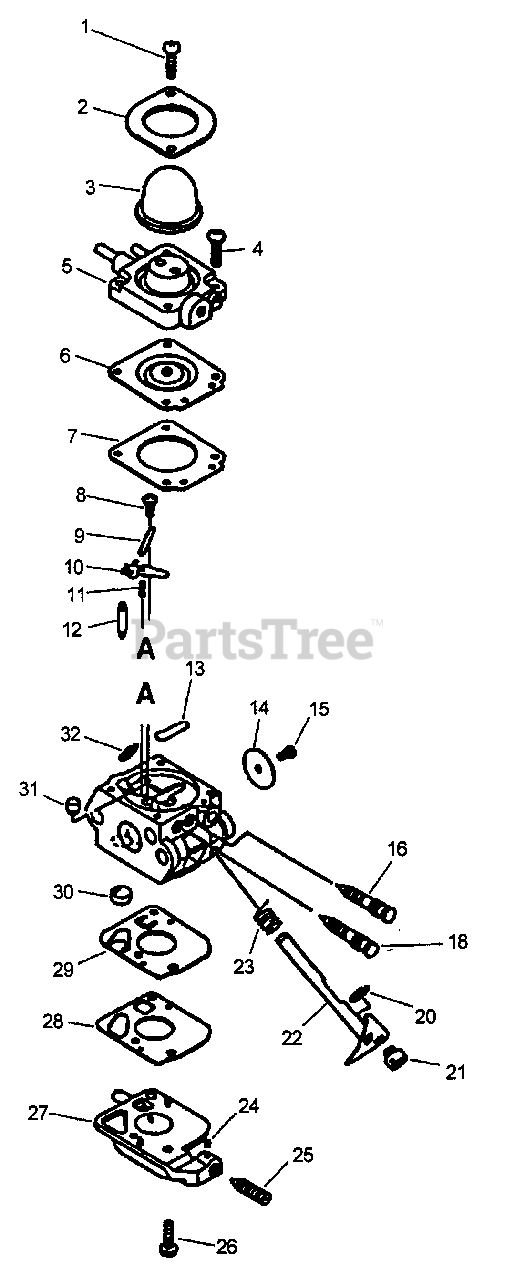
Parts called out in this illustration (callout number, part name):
2	RETAINER, PURGE BULB
3	BULB, PURGE
5	BODY ASSY, PURGE
6	DIAPHRAGM, METERING
7	GASKET, METERING DIAPHRAGM
9	BASE, PURGE
10	BASE, PURGE
11	BASE, PURGE
12	BASE, PURGE
13	BASE, PURGE
14	VALVE, THROTTLE
16	NEEDLE, MIXTURE
18	NEEDLE, HIGH SPEED
22	SHAFT, THROTTLE
23	SPRING, THROTTLE RETURN
24	PIECE, FRICTION
25	SCREW, IDLE ADJUST
27	COVER, FUEL PUMP
28	GASKET, FUEL PUMP
29	DIAPHRAGM, PUMP
30	BASE, PURGE
31	NOZZLE, CHECK VALVE
A	REBUILD KIT
B	GASKET / DIAPHRAGM KIT
